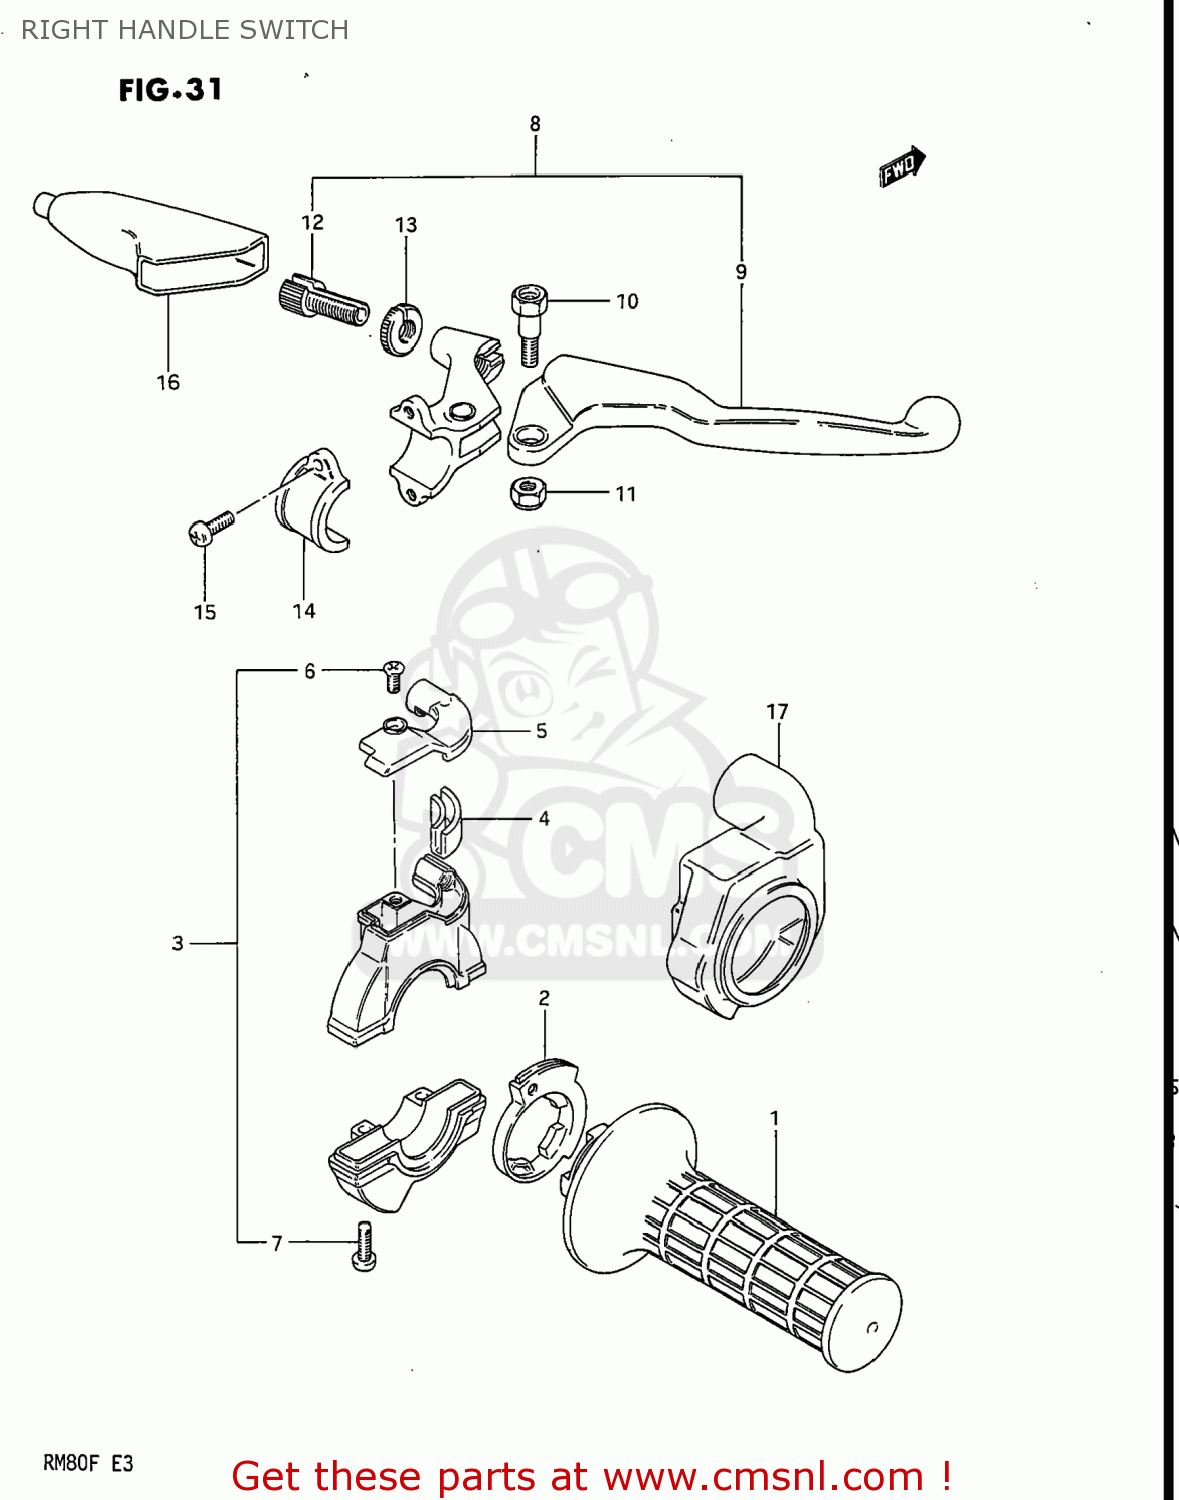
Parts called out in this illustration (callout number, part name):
1	GRIP,THROTTLE
2	ROTOR,THROTTLE GRIP
3	CASE ASSY,THROTTLE
4	GUIDE PIECE,THROTTLE
5	COVER,THROTTLE CASE
6	SCREW
7	SCREW
8	LEVER ASSY,BRAKE
9	LEVER,BRAKE
10	BOLT,LEVER
11	NUT 6MM
12	ADJUSTER,CABLE
13	NUT,CABLE ADJUSTER
14	BRACKET,CLUTCH LEVER HOLDER
15	SCREW
16	COVER,CLUTCH LEVER
17	COVER,THROTTLE CASE
